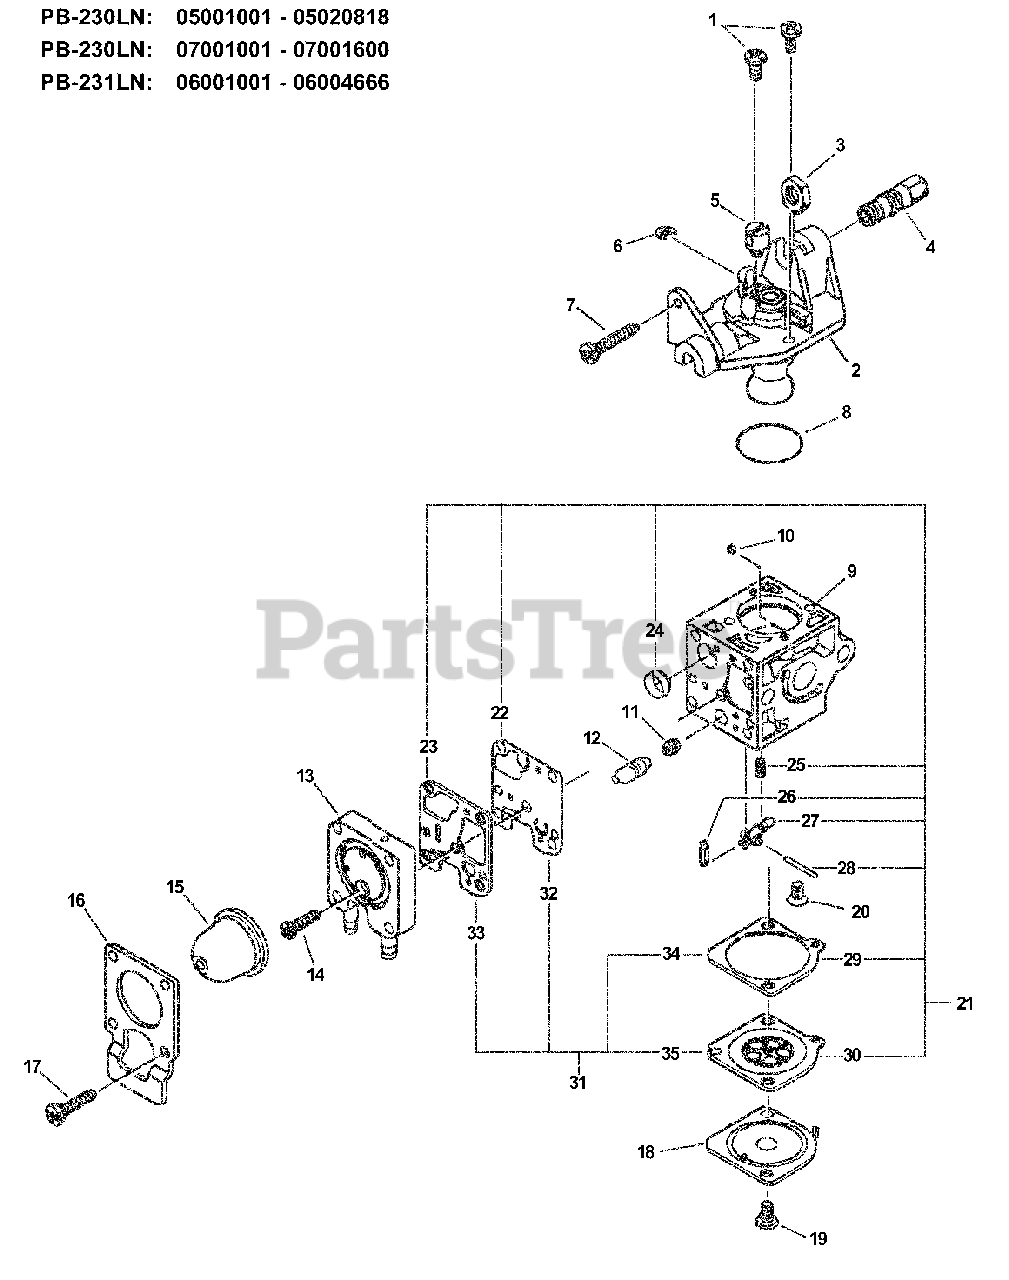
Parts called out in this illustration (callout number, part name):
2	ROTOR COVER ASSY
4	ADJUSTER, THROTTLE CABLE
7	SCREW, IDLE ADJUST
9	BODY, CARBURETOR
10	GUIDE, ROLLER
11	JET, MAIN
12	PLUG KIT
13	BODY ASSY, PURGE
15	BULB, PURGE
16	RETAINER, PURGE BULB
17	SCREW, PURGE BULB RETAINER
18	COVER, METERING DIAPHRAGM
20	SCREW
21	REBUILD KIT
22	DIAPHRAGM, PUMP
23	GASKET, PUMP
24	STRAINER
25	SPRING, METERING LEVER
26	VALVE, INLET NEEDLE
27	LEVER, METERING
28	PIN, METERING LEVER
29	GASKET, METERING
30	DIAPHRAGM, METERING
31	GASKET / DIAPHRAGM KIT
32	DIAPHRAGM, PUMP
33	GASKET, PUMP
34	GASKET, METERING
35	DIAPHRAGM, METERING
